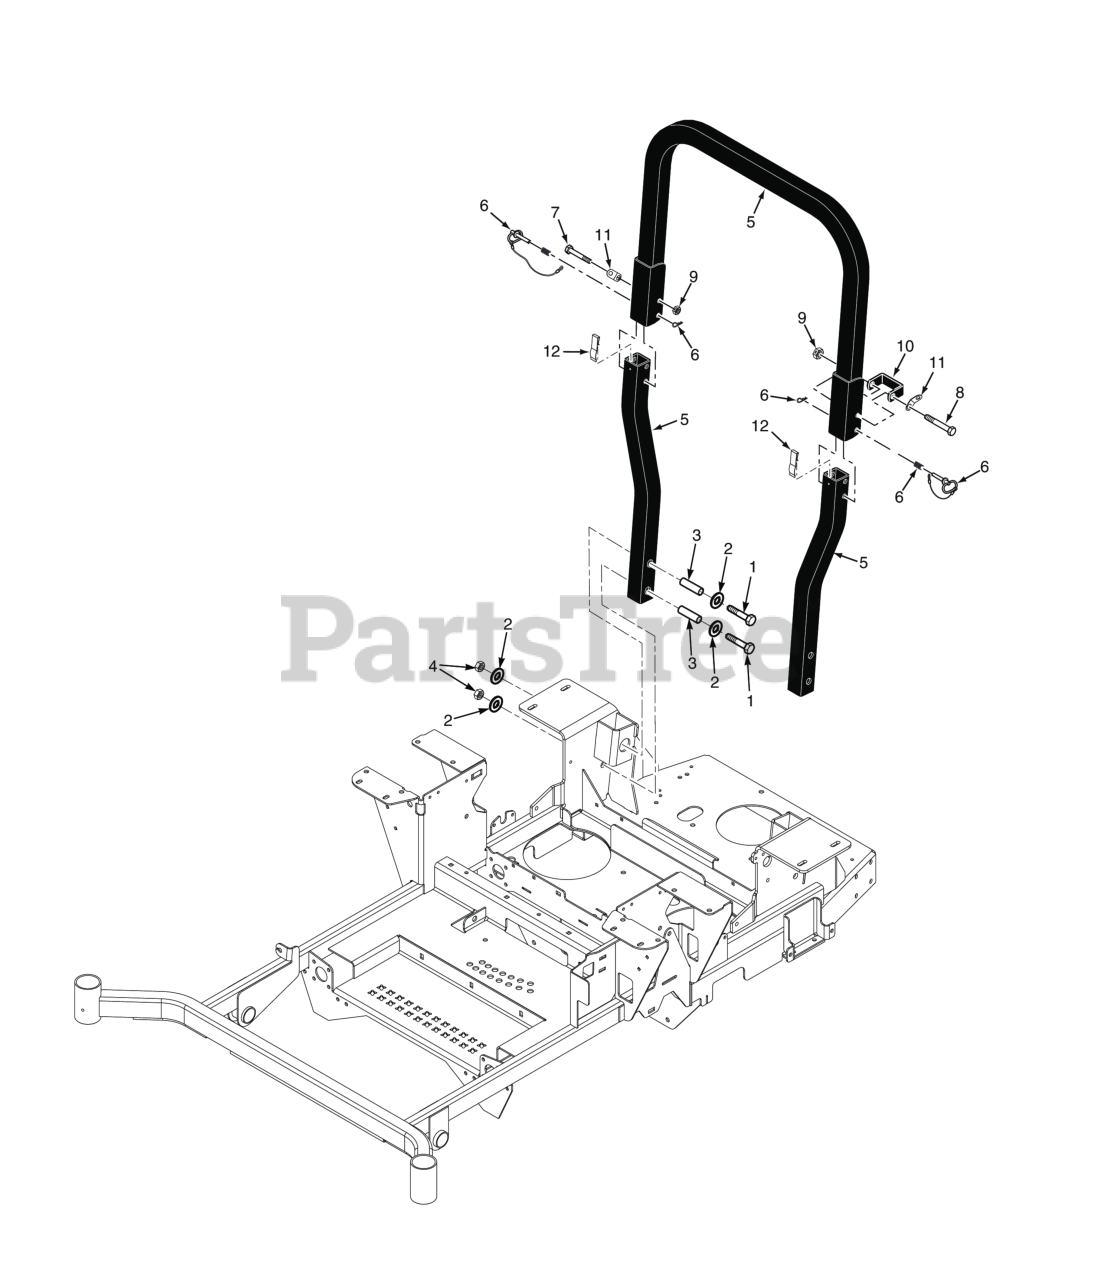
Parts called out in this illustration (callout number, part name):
1	Bolt, Hex Head 1/213 x 3" Gr. 8
2	Flatwasher, 1/2 - .531 x 1.062 x .095
3	Bushing, SFZ ROPS
4	Nut, Elastic Stop 1/2-13, (STT-52 & STTII-52)
5	ROPS, (Black)
5	ROPS, (Scag Gold)
6	Pin Assembly, ROPS Hinge
7	Bolt, Hex Head, 1/2-13 x 3-1/4"
8	Bolt, Hex Head 1/2-13 x 3-1/2"
9	Locknut, Hex 1/2-13 Center Lock
10	Stop, ROPS
11	Clip, ROPS
12	Spring, ROPS Anti-Rattle
